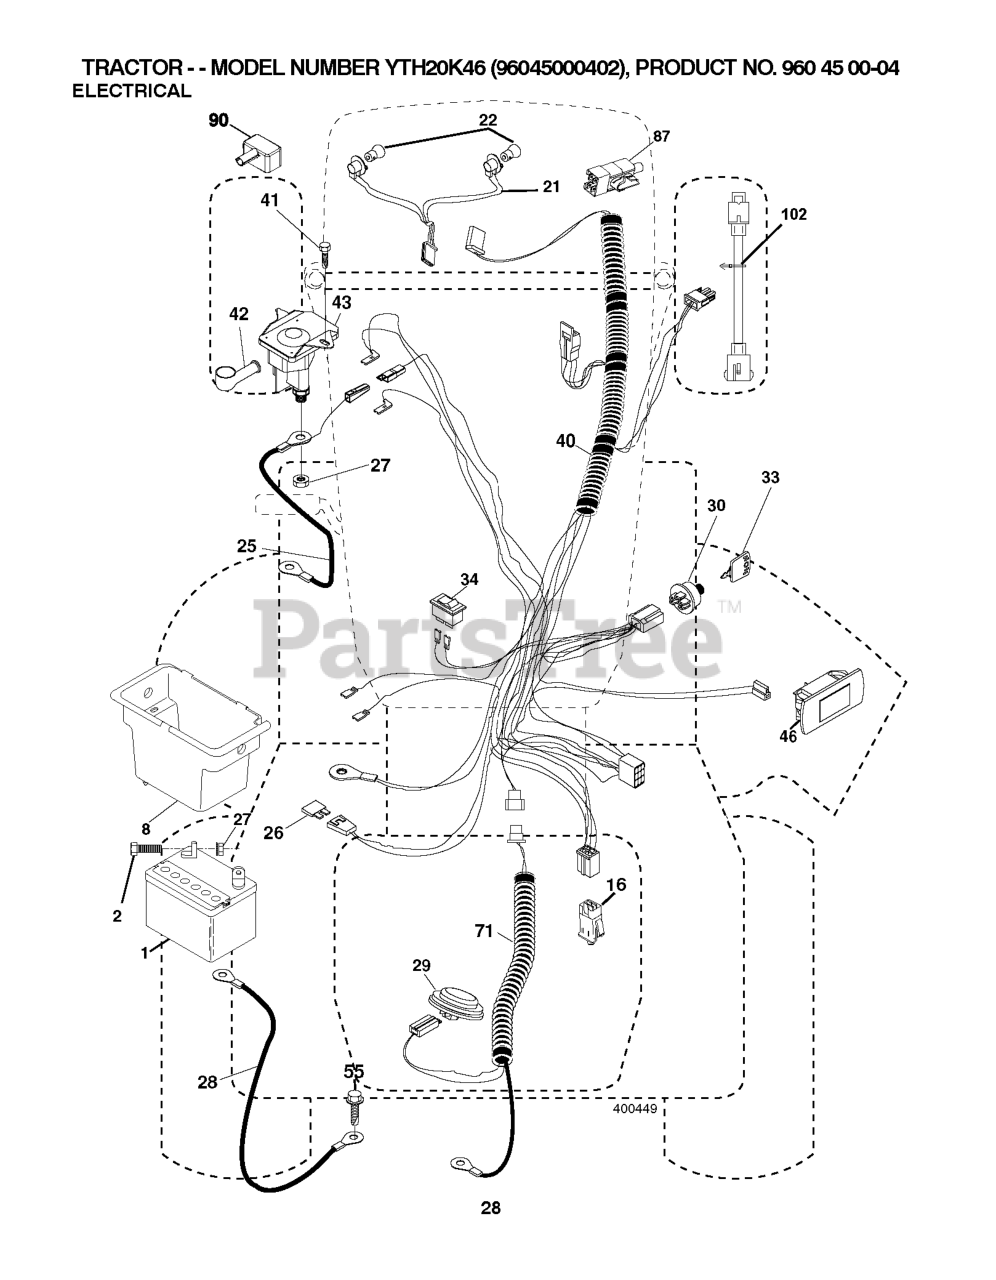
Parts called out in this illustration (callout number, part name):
1	Battery 12 Volt 25 Amp
2	BOLT.HEX.1/4.X.3/4.DICHROMATE
8	BOX.BATTERY.MNT.REAR.L
16	SWITCH INTERLOOK PUSH-IN
21	HARNESS ASSY LIGHT
25	CABLE.START.RED.17.5".
26	FUSE 20AMP
27	NUT
28	CABLE.BLACK.18"REAR.BA
29	SWITCH.SEAT.DELTA.OPC.
30	SWITCH.IGN.DELTA.W.LGH.ROS
33	KEY MLD GEN DELTA
40	HARNESS.IGN.CHASS.TEX.REAR.BAT
41	SCREW
42	TERMINAL COVER
43	SOLENOID.W/BRASS.PLUNGER
46	RP.GUAGE.SRVCMNDR.HRMTR.
55	SCREW 5/16"
71	HARNESS IGN. DASH
87	SWITCH.INTRLCK.CLUTCH.
90	COVER, TERMINAL BATTERY
102	HARNESS PIGTAIL PCH TEX ROS
